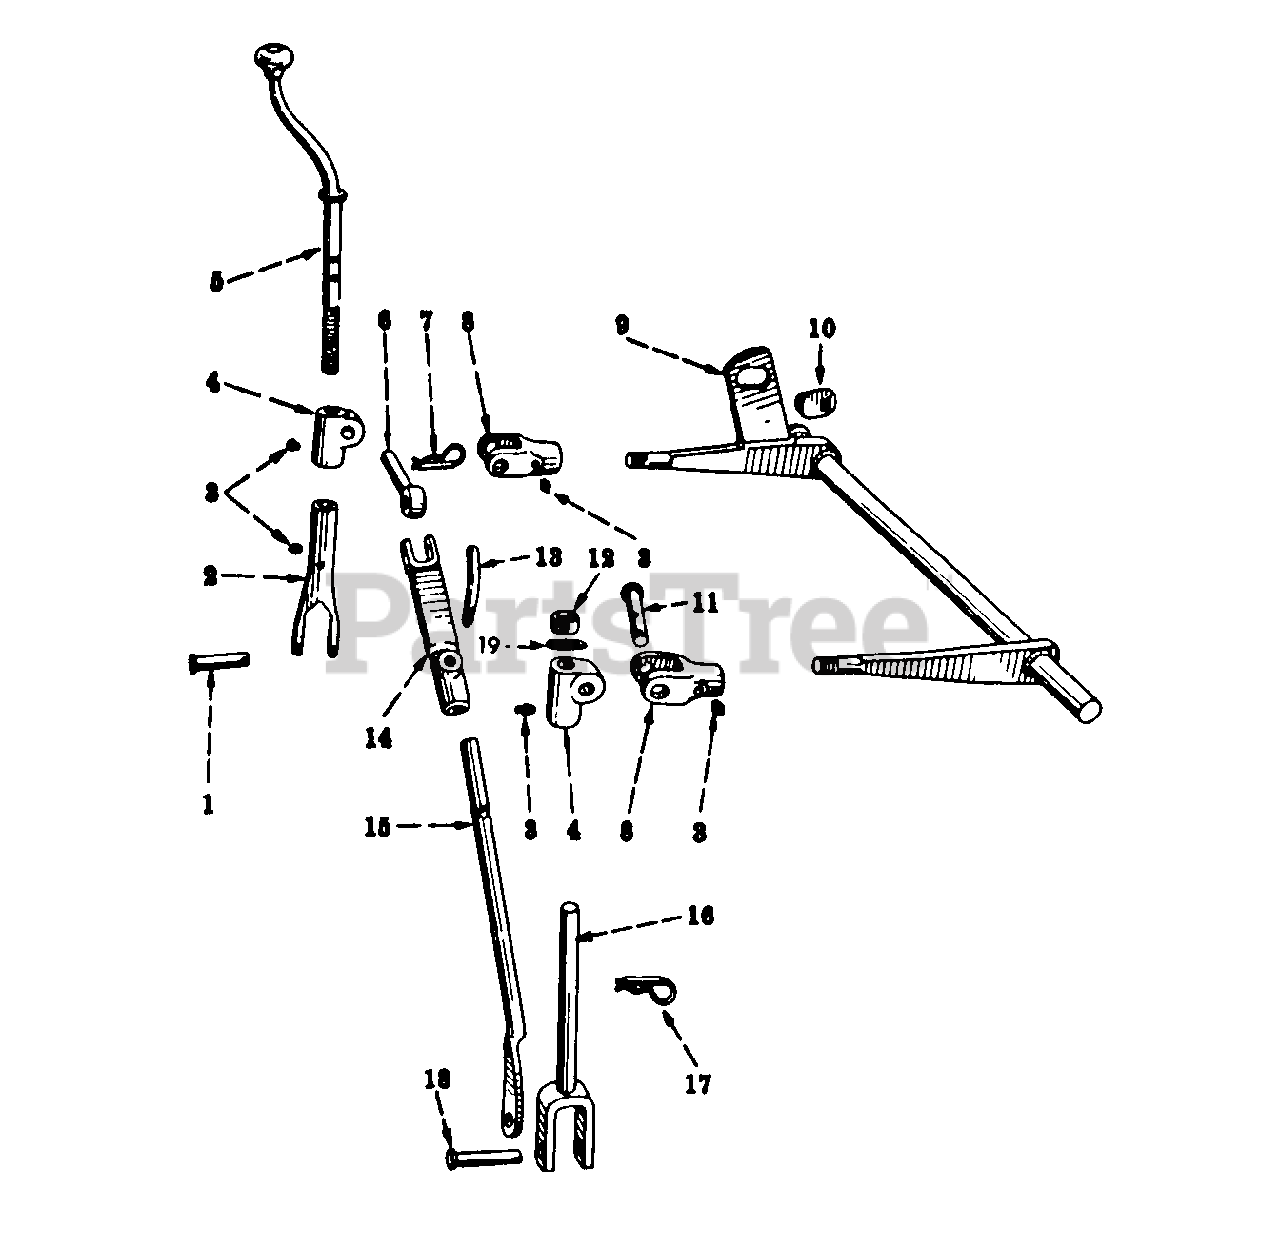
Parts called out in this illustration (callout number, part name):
1	PIN, 3/4 X 3 STD-HD DRILLED
2	HOUSING, LEVELING SCREW
3	FITTING, 1/8-27 STR LUB
4	SWIVEL, UPPER LATERAL LINK
5	SCREW ASSY, LEVELING
6	SWIVEL, DIAGONAL LINK
7	PIN ASSY, QUICK-ATTACHABLE COT.
8	SWIVEL, ROCKSHAFT ARM
9	ROCKSHAFT ASSY
10	BUSHING, LIFT ARM
11	PIN, ROCKSHAFT ARM RH PIVOT
12	COLLAR, LATERAL LINK
13	BOLT, DIAGONAL LINK STOP LOCK
14	STOP, DIAGONAL LINK
15	LINK, DIAGONAL
16	LINK ASSY, LATERAL
17	PIN ASSY, QUICK-ATTACHABLE COT
18	PIN, LATERAL LINK
19	SHIM, SCREW OR LATERAL LINK LEVELING -22 GA-
